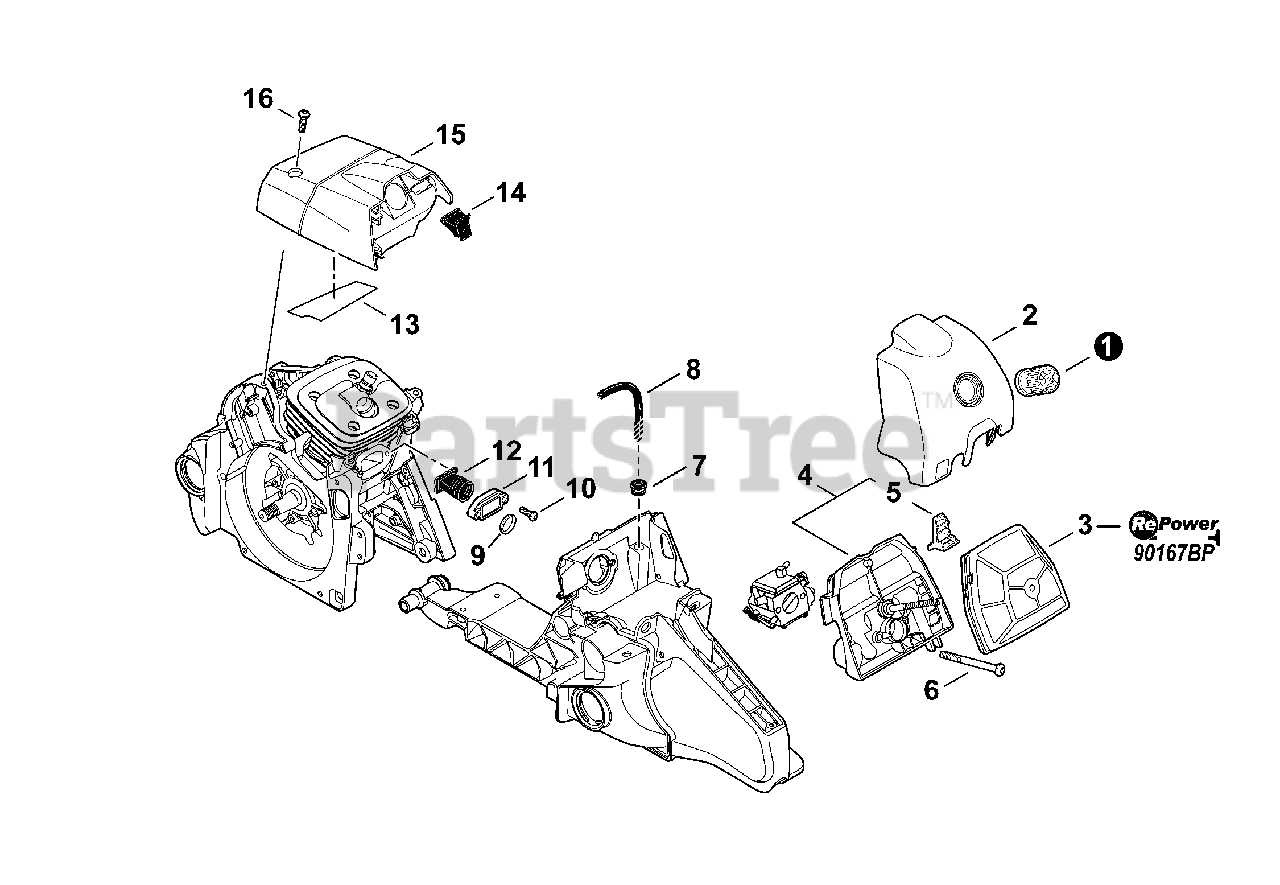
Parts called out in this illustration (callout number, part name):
1	KNOB, AIR FILTER COVER
2	COVER, AIR FILTER
3	FILTER ASSY, AIR
4	CASE ASSY, AIR FILTER
5	SHUTTER, AIR
6	BOLT, TORX 5×50
7	GROMMET
8	PIPE, IMPULSE 3×6(8)×160
9	COLLAR 18.6×20.4×4
10	BOLT, TORX 5×16
11	HOLDER, BELLOWS
12	BELLOWS, INTAKE
13	SHIELD, HEAT 75×32×0.15
14	PIPE, INTAKE
15	COVER, ENGINE
16	BOLT, TORX 5×16
